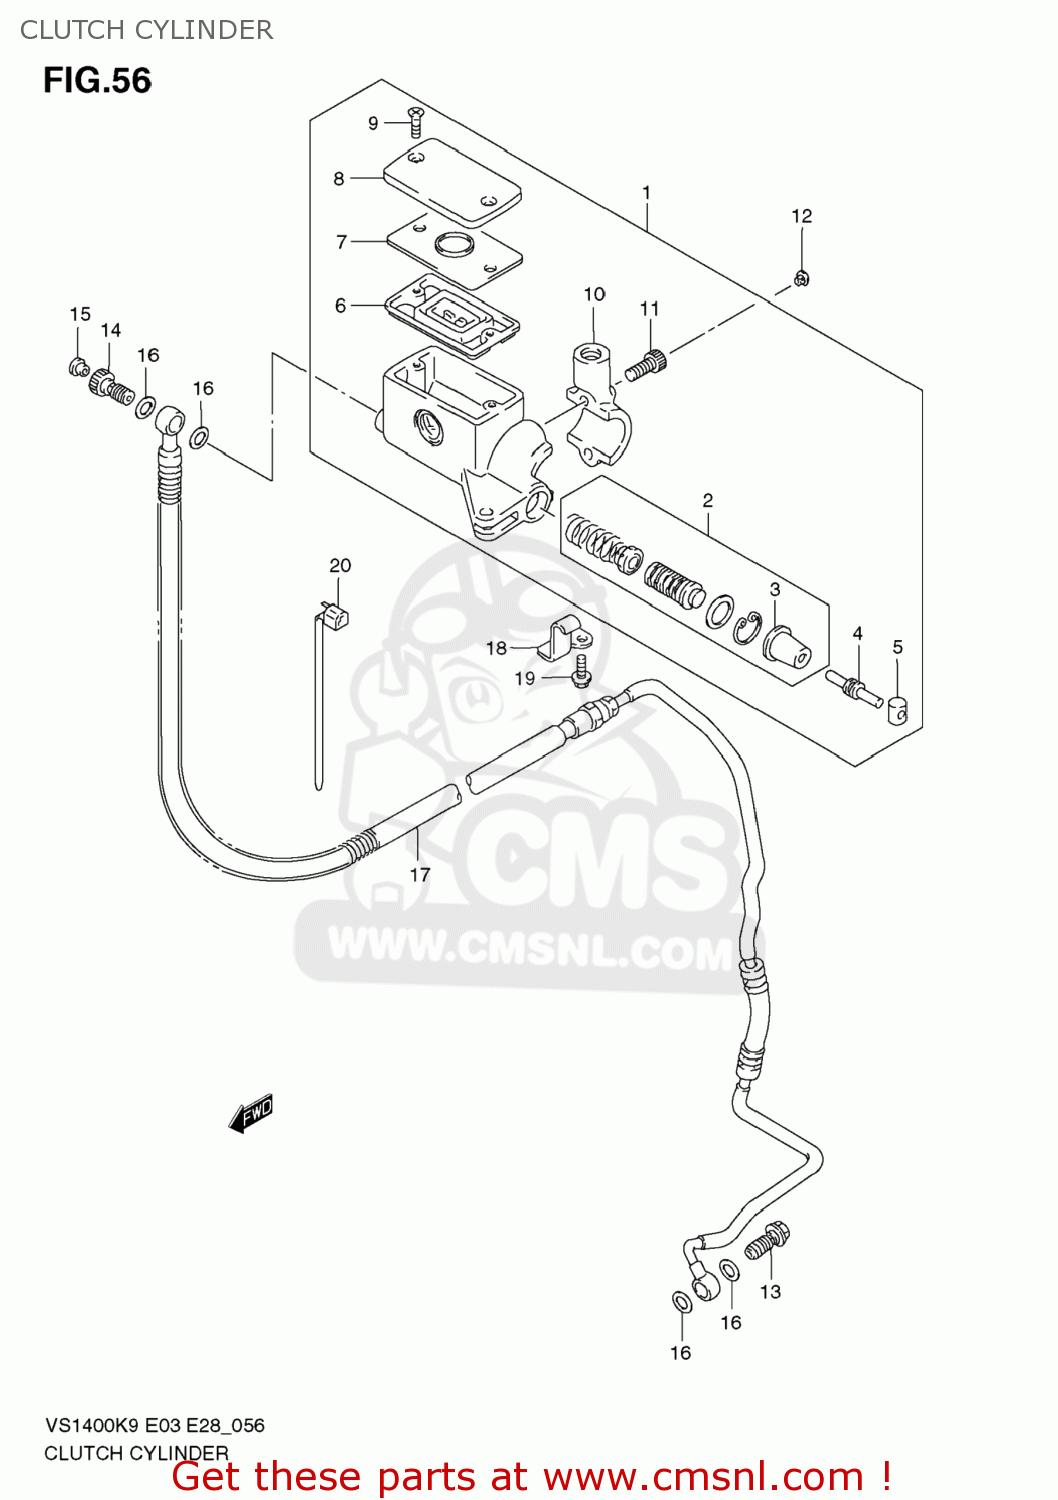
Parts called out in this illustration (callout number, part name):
1	CYLINDER ASSY, CLUTCH MASTER
2	PISTON & CUP SET
3	BOOT
4	PUSH ROD
5	BUSH
6	7
7	PLATE,DIAPHRAGM
8	CAP
9	SCREW
10	HOLDER
11	BOLT
12	CAP(OD:10)
13	BOLT UNION
14	BOLT UNION
15	CAP(OD:12)
16	WASHER(10X15X1.5)
17	HOSE ASSY,CLUTCH
18	CLAMP,CLUTCH HOSE
19	BOLT
20	CLAMP(L:165)
